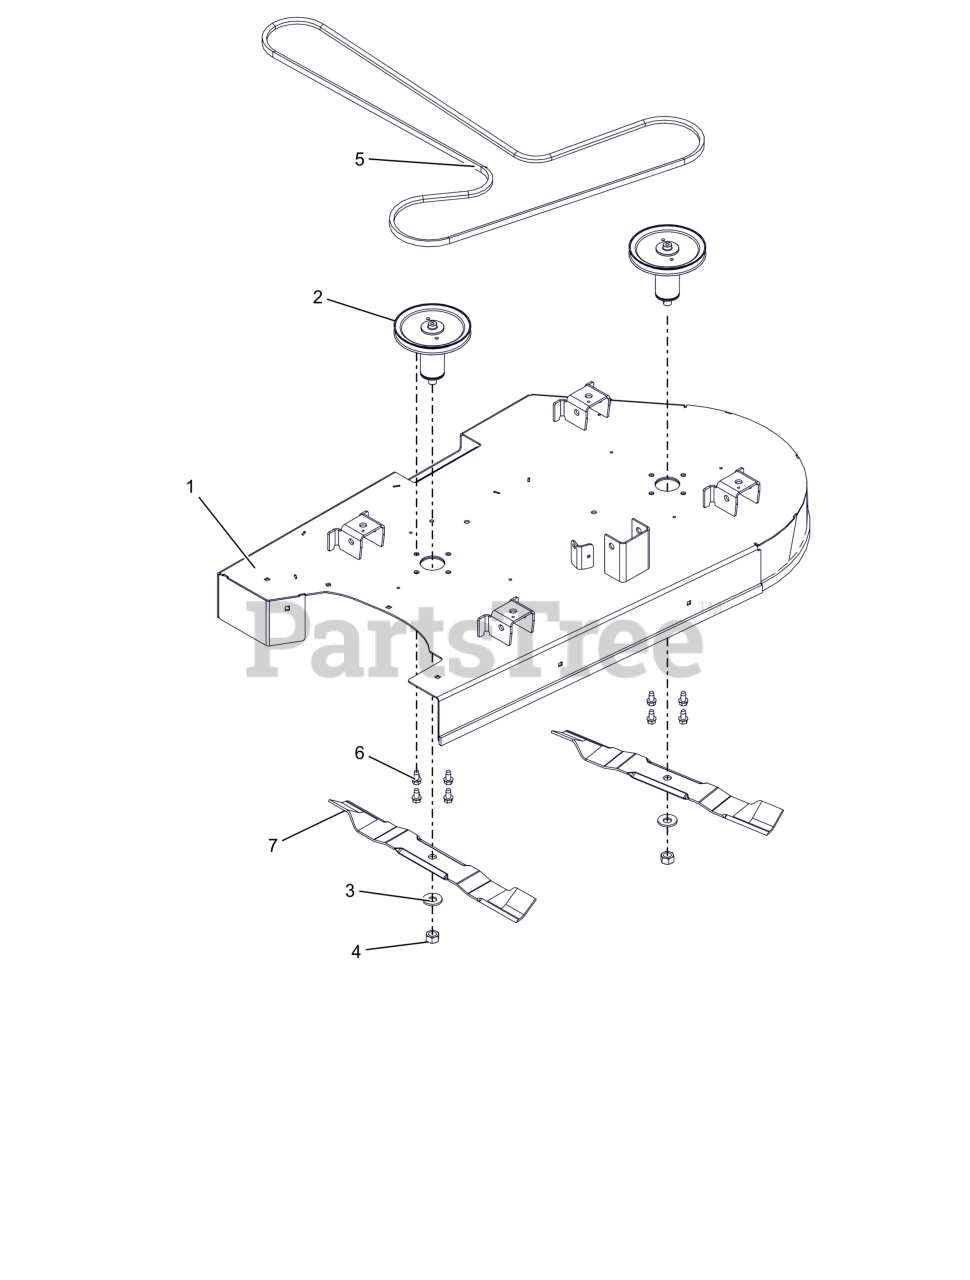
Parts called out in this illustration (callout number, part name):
1	KIT, 42" EDGE DECK W/DECALS
2	KIT, DECK SPINDLE ASM-60
3	WSHR-BLVL .669X1.535X.138
4	NUT-STD .625-18 ZCC
5	V-BELT, HA-WRAPPED
6	SCR,TAP .375-16X.75 HWH TR ZCC
7	BLADE, 21" 35 DEG
